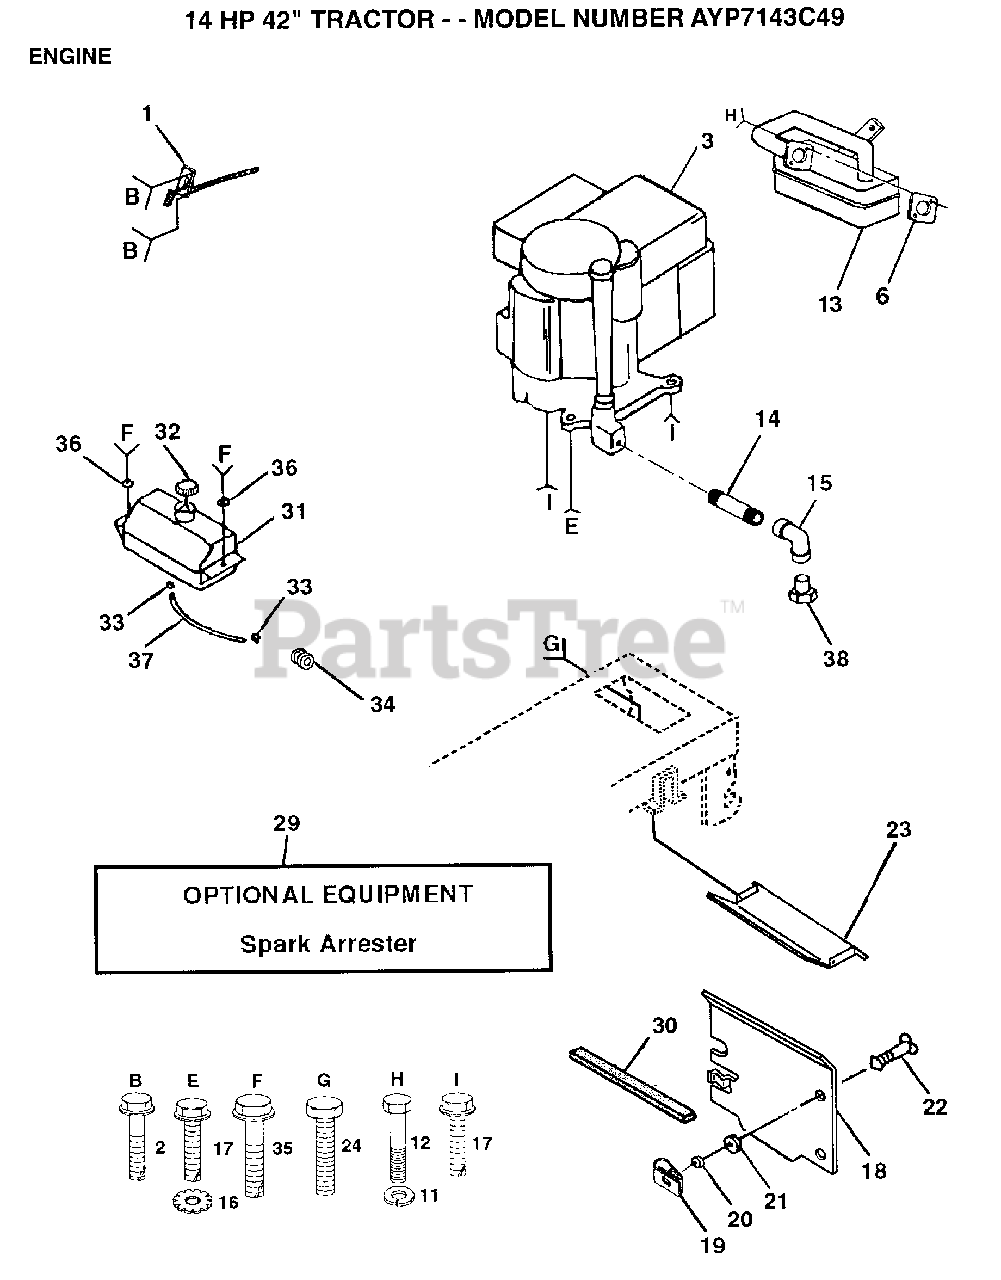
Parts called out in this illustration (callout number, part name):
2	SCREW LT
11	LOCKWASHER
12	SCREW
13	MUFFLER
14	PIPE NIPPLE
15	ELBOW
16	LOCKWASHER
17	SCREW
18	SHIELD HEAT
19	RECEPTACLE LT
20	RETAINER LT
21	WASHER
22	STUD.1/4.TURN
23	HEAT SHIELD
24	SCREW
31	TANK.FUEL.LT.
32	CAP ASM FUEL
33	HOSE CLAMP
35	SCREW HEX CRT
36	WASHER
37	LINE FUEL
